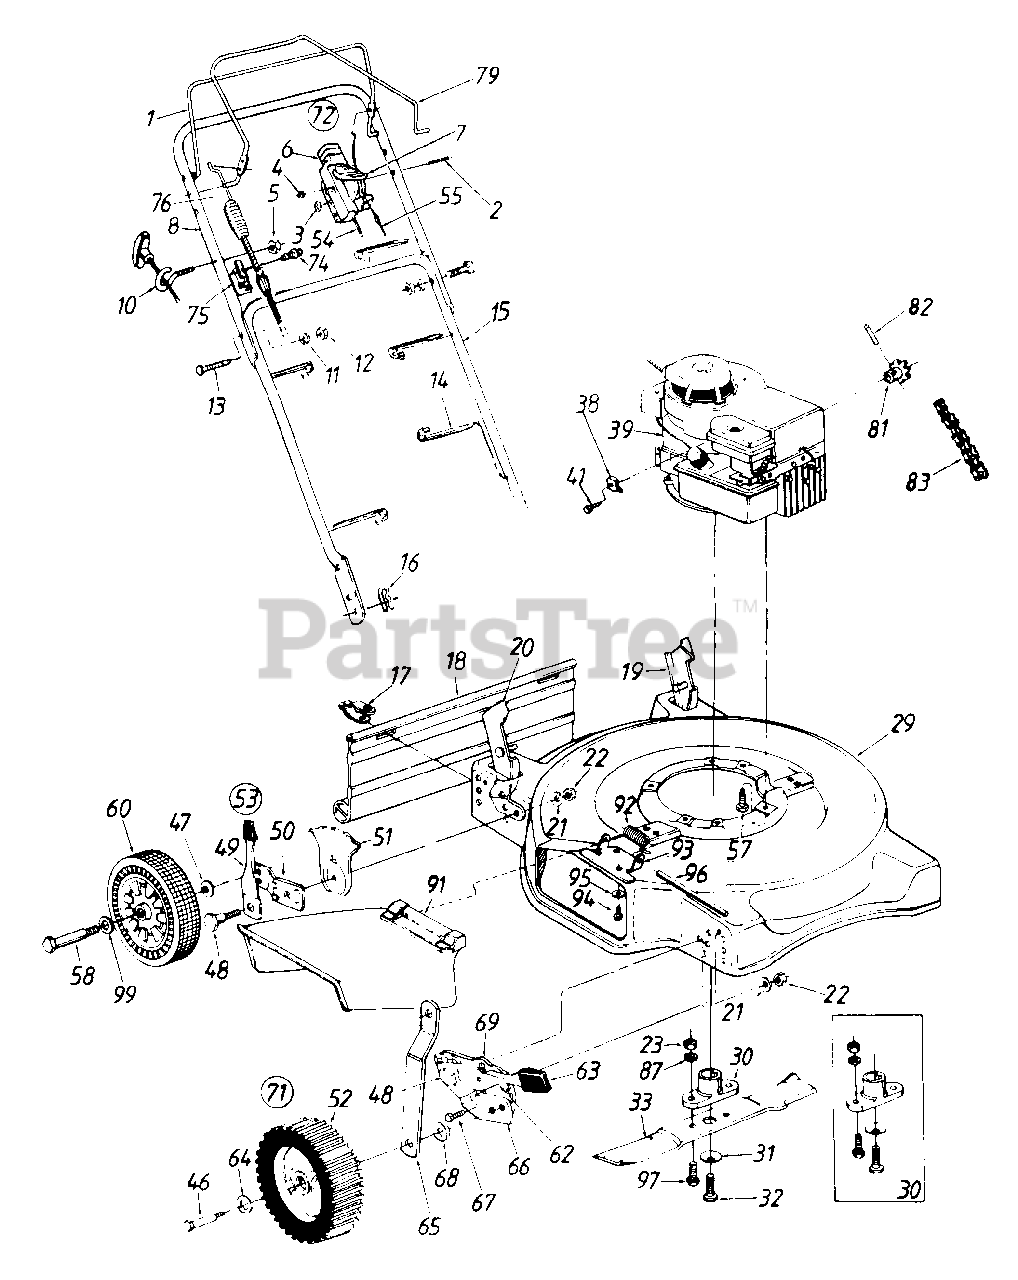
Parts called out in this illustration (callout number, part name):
2	Oval C-Sunk Mach. Scr.
3	Spr. Wash..66" I.D.
4	Hex L-Nut 1/4-20 Thd.
5	Hex L-Nut 1/4-20 Thd.
6	Throttle Body
7	Throttle Lever
8	Upper Handle
10	Rope Guide
11	L-Wash. 5/16" I.D.
12	Hex Nut 5/16-18 Thd.
13	Curved Carriage Bolt 5/16-18 x 1.38" Lg.
14	Cable Tie
15	Lower Handle
16	Hairpin Cotter
17	Hinge Clip
18	Rear Flap
19	Handle Bracket Ass'y.- L.H.
20	Handle Bracket Ass'y.- R.H.
21	Bell-Wash..39" I.D. x 1.38"
22	Hex Nut 3/8-16 Thd.
23	Hex Nut 3/8-24 Thd.
29	22" Deck Ass'y.
30	Blade Adapter Kit
31	Bell-Wash..39" I.D.
32	Hex Bolt 3/8-24 x 1.5" Lg.
33	22" Blade
38	Cable Clamp
39	Engine
41	Hex Wash. Hd. Scr. #10-32 x .62" Lg.
46	Front Axle Bolt
47	Bell-Wash..400" I.D. x .88"
48	Shld. Bolt .50" Dia. x .357"
49	Spring Lever Ass'y. w/Knob
51	Height Adj. Plate
52	Front Wheel Ass'y. Comp.
53	Height Adj. Ass'y. Comp.- R.H.
54	Throttle Control Wire 51" Lg.
55	Control Cable - 39"
57	Hex L-Wash. Hd. Scr. 3/8-16 x 1.0" Lg
58	Rear Axle Bolt
60	Rear Wheel Ass'y. Comp.
62	Spring Lever
63	Spring Lever Knob
64	Fl-Wash..531" I.D. x .93"
67	Hex AB-Tap 1/4-.62" Lg.
68	Bell-Wash..380" I.D. x .88"
69	Index Plate
71	Front Height Adj. Ass'y.- R.H.
72	Throttle Box Comp.
74	Hex
75	Cable Brkt.
76	Clutch Cable w/Spring - 47"
82	Spring Pin Spir. 3/16" Dia. x 1" Lg.
83	#48 Chain 1/2" Pitch 50 Links (Endless)
87	L-Wash. 3/8" I.D.
91	Chute Deflector Ass'y.
92	Torsion Spring
93	Adapter Plate
94	Hex
95	Bell-Wash. 1/4" I.D.
96	Hinge Pin
97	Hex Bolt 3/8-24 x 1" Lg.
99	Wave Wash..53" I.D. x .78"
